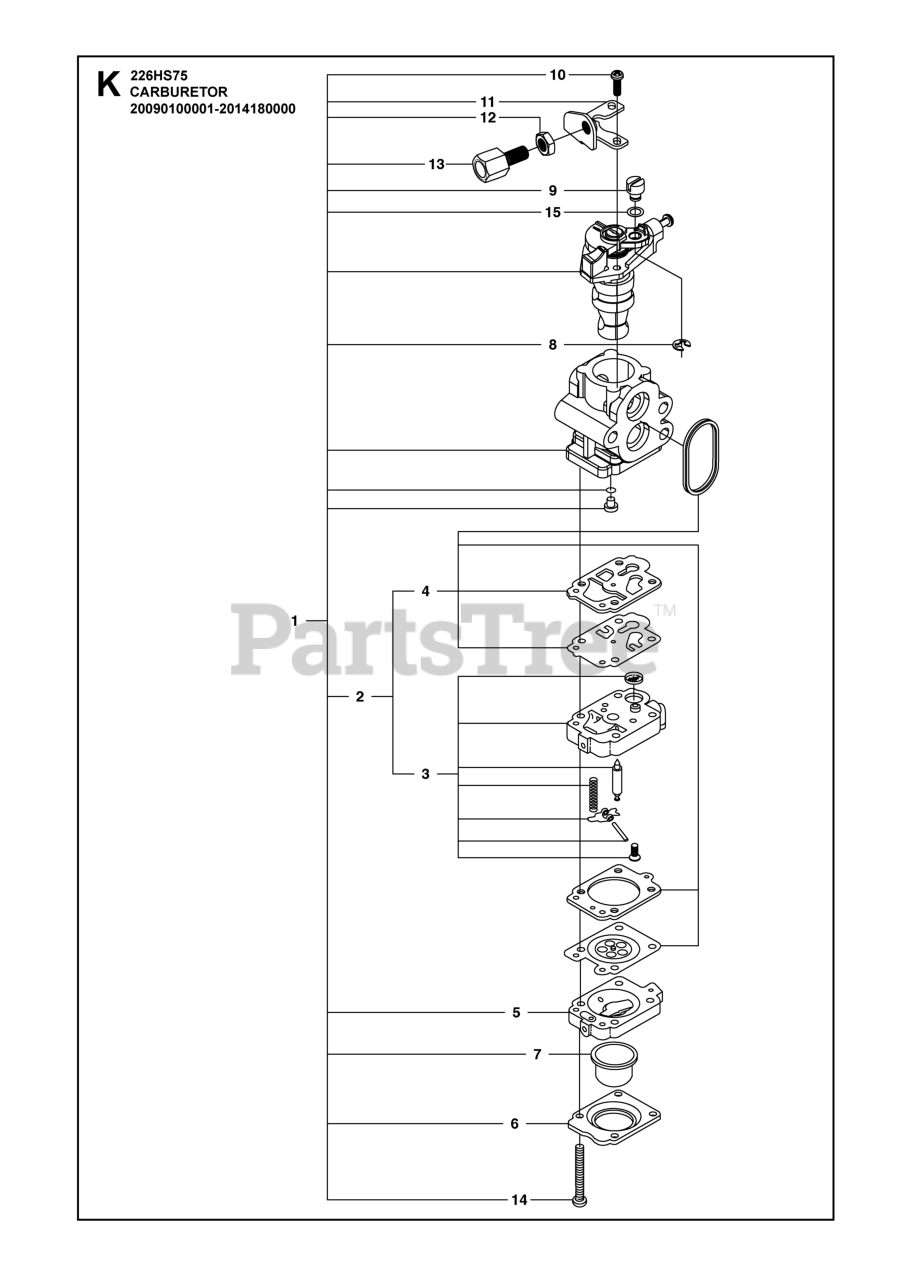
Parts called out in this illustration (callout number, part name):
1	CARBURETOR ASSY
2	REBUILD KIT
3	CARBURETOR BODY
4	GASKET KIT
12	NUT
13	ADJUSTER
